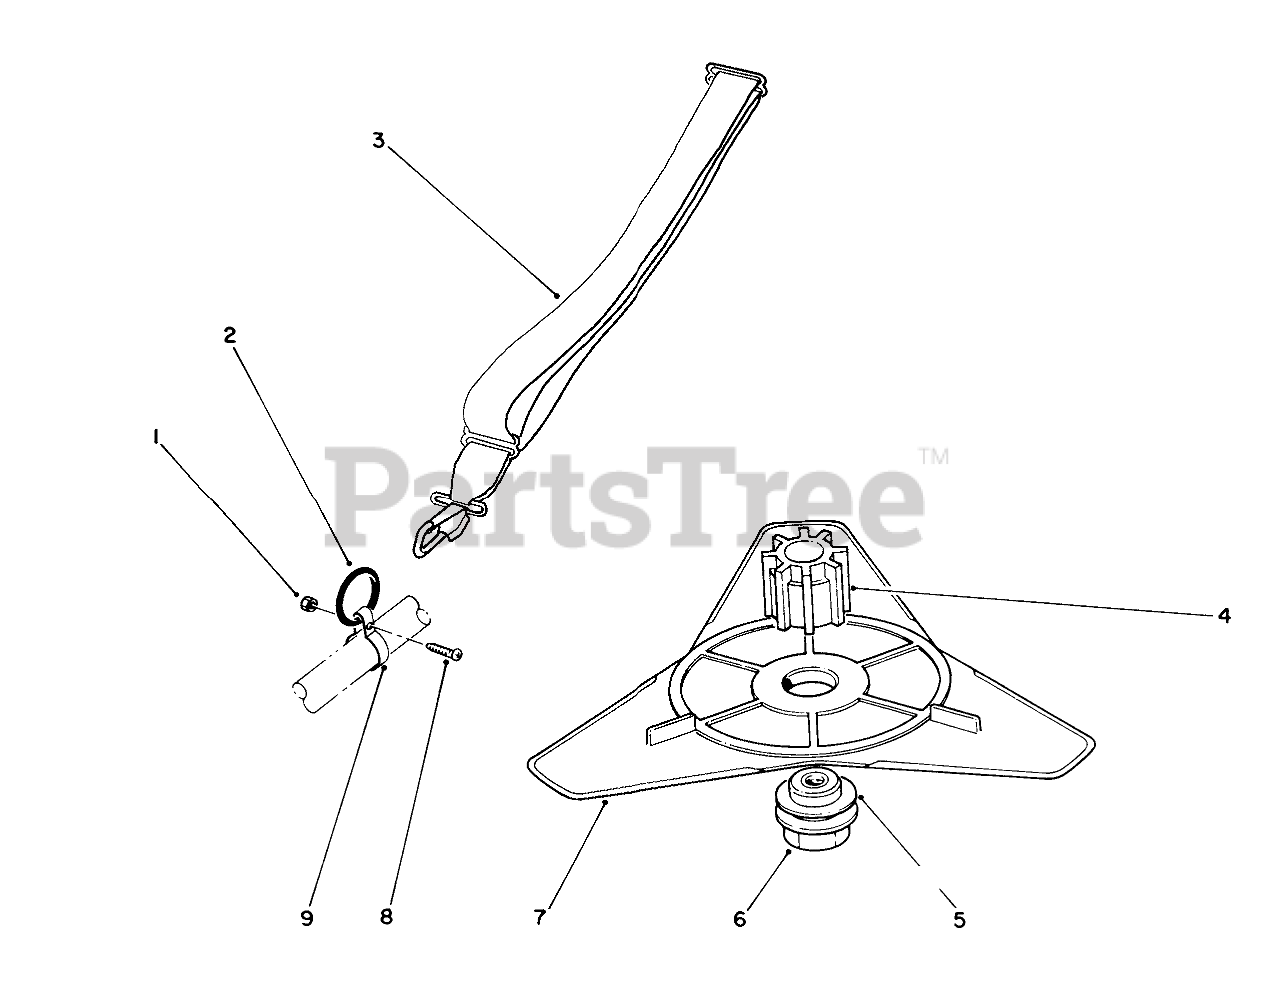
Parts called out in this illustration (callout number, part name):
1	NUT-LOCK, NI
2	RING-HARNESS
3	Harness
4	BLADE ADAPTER
5	FLAT WASHER
6	ADAPTER NUT
7	FLEX BLADE PKG
8	SCREW-SRH
9	Clamp
